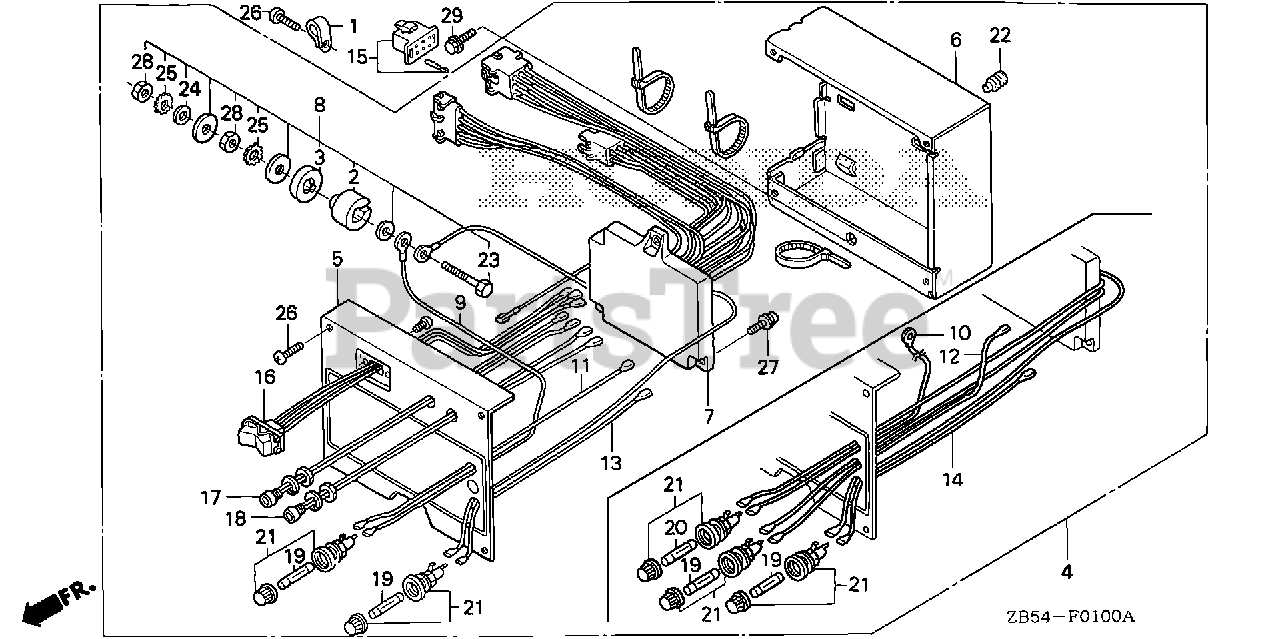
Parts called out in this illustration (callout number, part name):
1	CLAMP F, CABLE
2	COLLAR A, D.C. TERMINAL
3	COLLAR B, D.C. TERMINAL
4	BOX ASSY., CONTROL *NH192M* (GENTLY SILVER METALLIC) (N/A: USE ALTERNATE PART 31400-ZB5-831ZA)
4	BOX ASSY., CONTROL *NH192M* (GENTLY SILVER METALLIC) (NA USE ALT:31400-ZB5-831ZA)
5	PANEL, CONTROL *NH192M* (GENTLY SILVER METALLIC)
6	BOX, CONTROL
7	CONTROL ASSY. (USE ALTERNATE PART 31400-ZB5-831ZA)
7	CONTROL ASSY. (NOT AVAILABLE)
8	TERMINAL SET, BATTERY
9	WIRE A, FUSE HOLDER
10	WIRE A, FUSE HOLDER
11	WIRE B, FUSE HOLDER
12	WIRE B, FUSE HOLDER
13	WIRE C, FUSE HOLDER
14	WIRE C, FUSE HOLDER
15	CONNECTOR ASSY., PLUG
16	SWITCH, ENGINE
17	SOCKET ASSY., LAMP (GREEN)
18	SOCKET ASSY., LAMP (RED)
19	FUSE (3A)
19	FUSE (4A)
20	FUSE (10A) (NOT AVAILABLE)
21	HOLDER, FUSE
22	CUSHION, RR. FENDER
23	BOLT, B.C. TERMINAL
24	WASHER, D.C. TERMINAL
25	WASHER, STAR
26	SCREW, PAN (4X12)
27	SCREW-WASHER (4X12) Use up to Engine SN 2056819.
28	NUT, HEX. (8MM)
29	BOLT, FLANGE (6X12) Use up to Engine SN 1543277.
